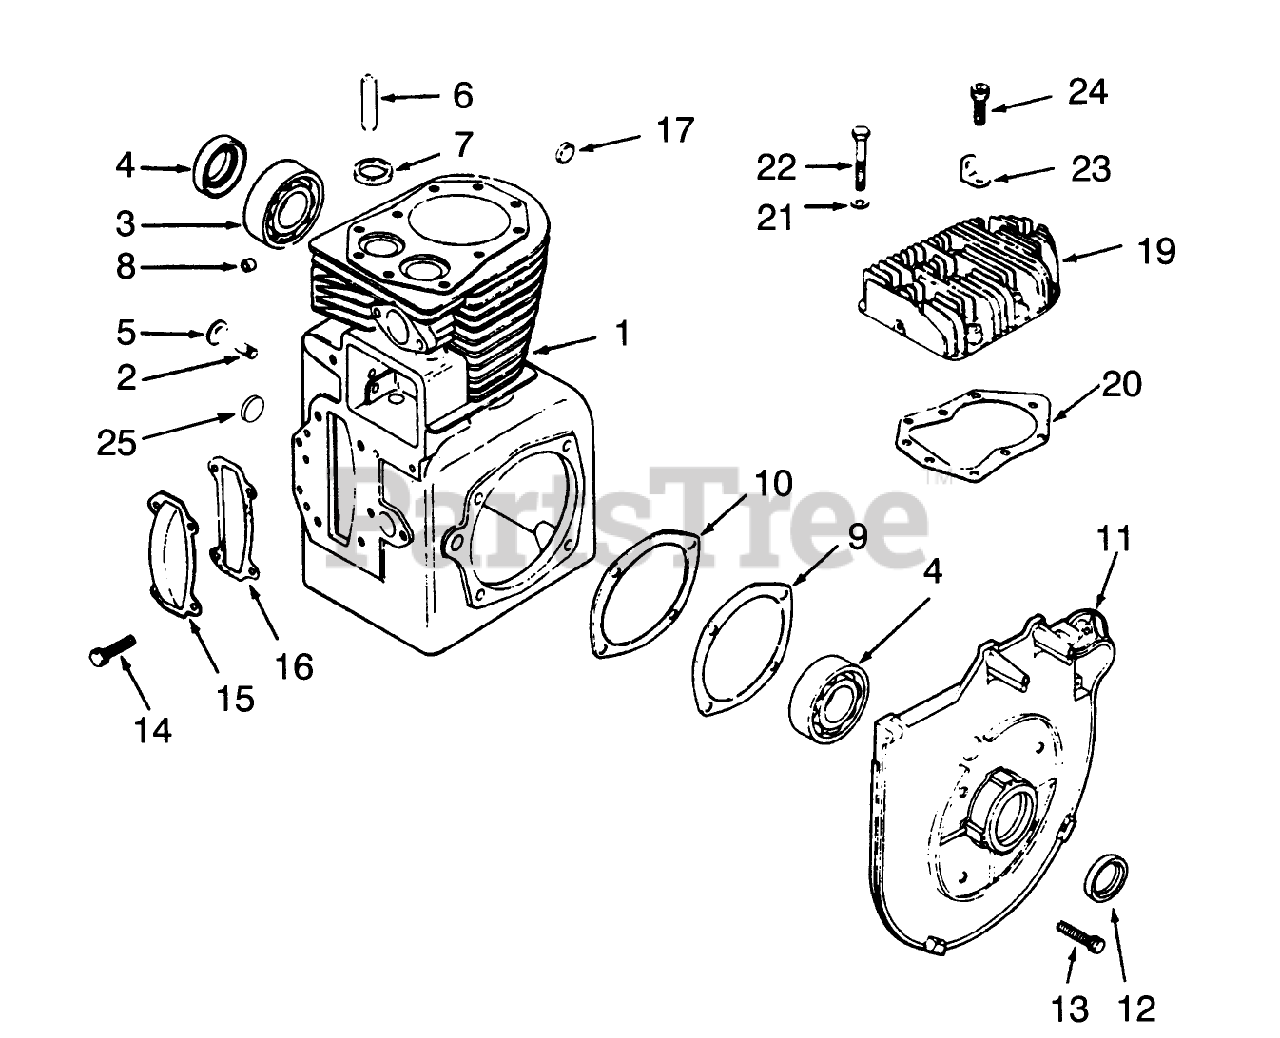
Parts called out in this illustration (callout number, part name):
1	KOHLER 47-522-94
2	KOHLER 235125-5
3	KOHLER 235376
4	KOHLER 47-032-07
5	KOHLER X-230-11
6	KOHLER 230007-5
7	KOHLER 230170
8	KOHLER 234866
9	KOHLER 47-041-09
10	KOHLER 47-522-05
11	KOHLER 47-146-11
12	KOHLER 47-032-06
13	KOHLER X-159-2
14	KOHLER X-132-6
15	KOHLER 235026
16	KOHLER 235025
17	KOHLER X-702-3
19	KOHLER 47-015-05
20	KOHLER 47-041-15
21	KOHLER 270889
22	KOHLER 270158
23	KOHLER 47-455-02
24	KOHLER 47-086-17
25	KOHLER 47-004-02
